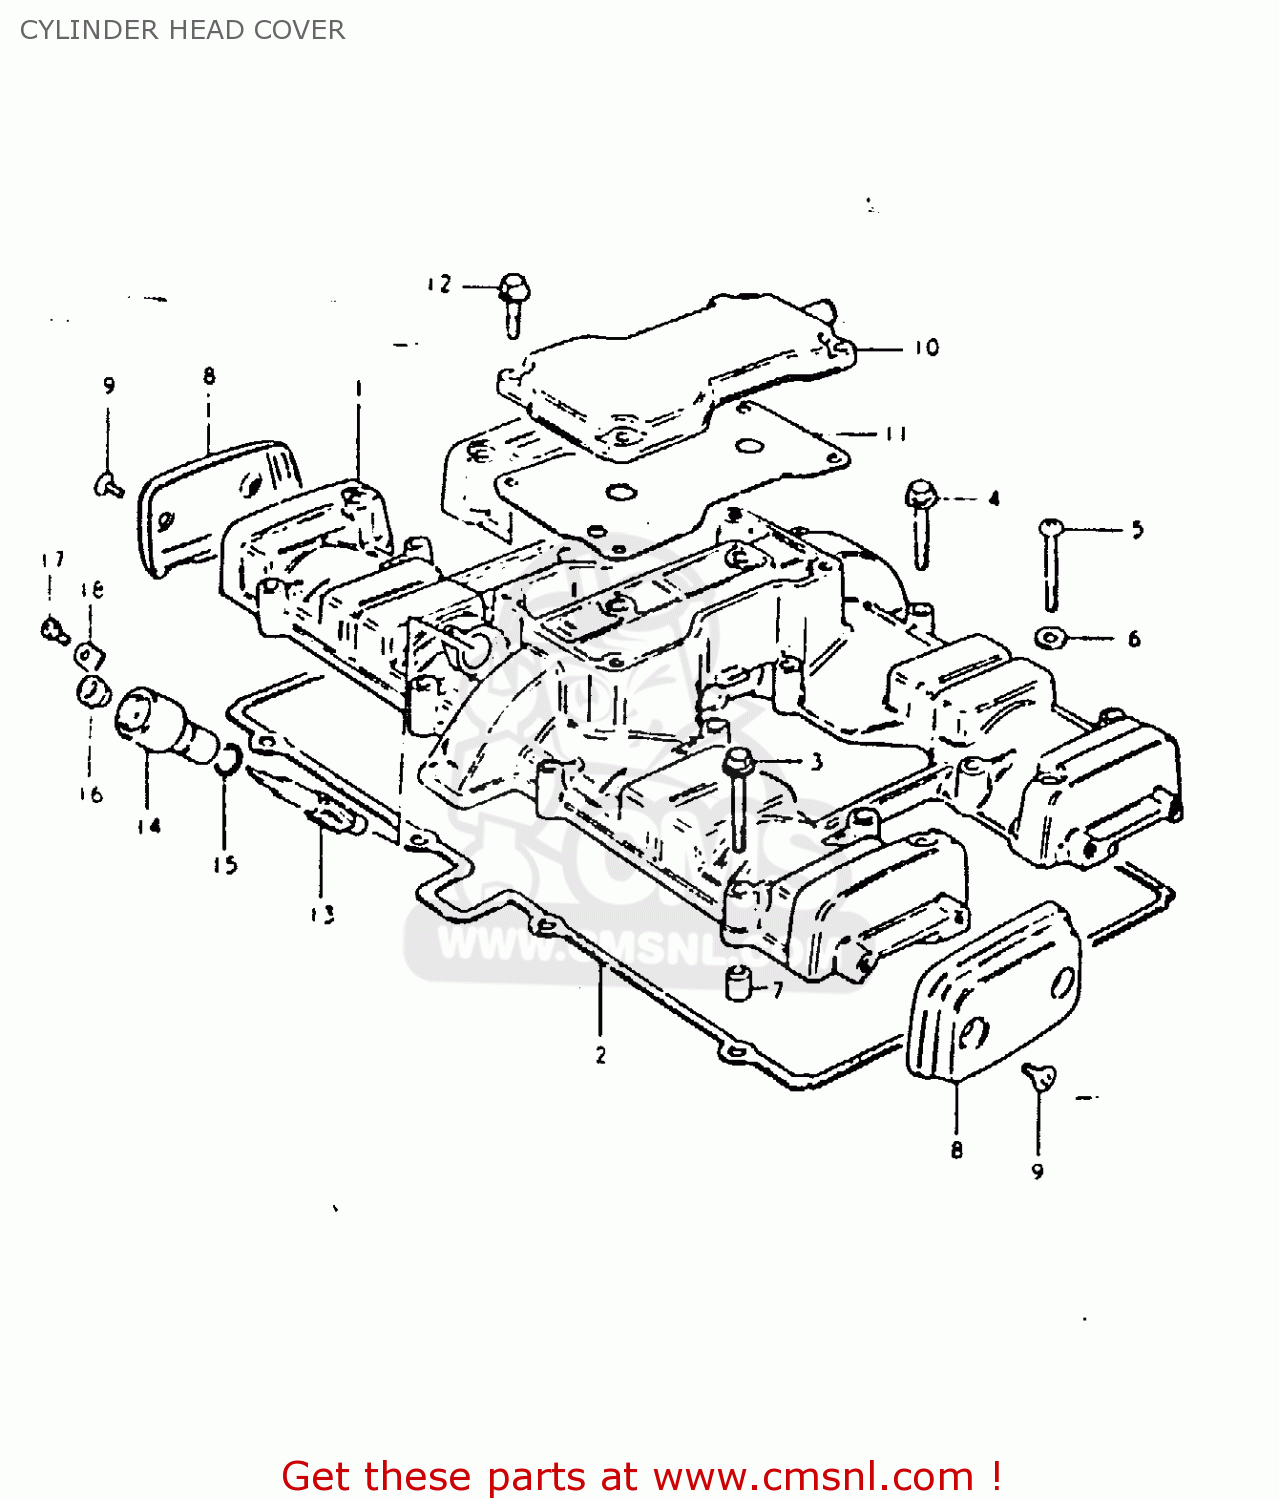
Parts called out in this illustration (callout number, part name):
1	COVER,CYLINDER HEAD
2	GASKET,CYLINDER HEAD COVER (MCA)
3	BOLT
4	BOLT 6X35
5	SCREW 6X40
6	GASKET (NAS)
7	PIN(6.2X8X11)
8	UNION,CYLINDER HEAD OIL
9	SCREW 5X12
10	COVER,BREATHER
11	GASKET (MCA)
12	BOLT,REAR
13	GEAR,TACHOMETER DRIVEN
14	SLEEVE,TACHOMETER DRIVE
15	SEAL,TACHOMETER DRIVEN
16	SEAL,OIL(5X12X8)
17	SCREW(5X12)
18	PLATE,TACH DRIVE GEAR SLEEVE
